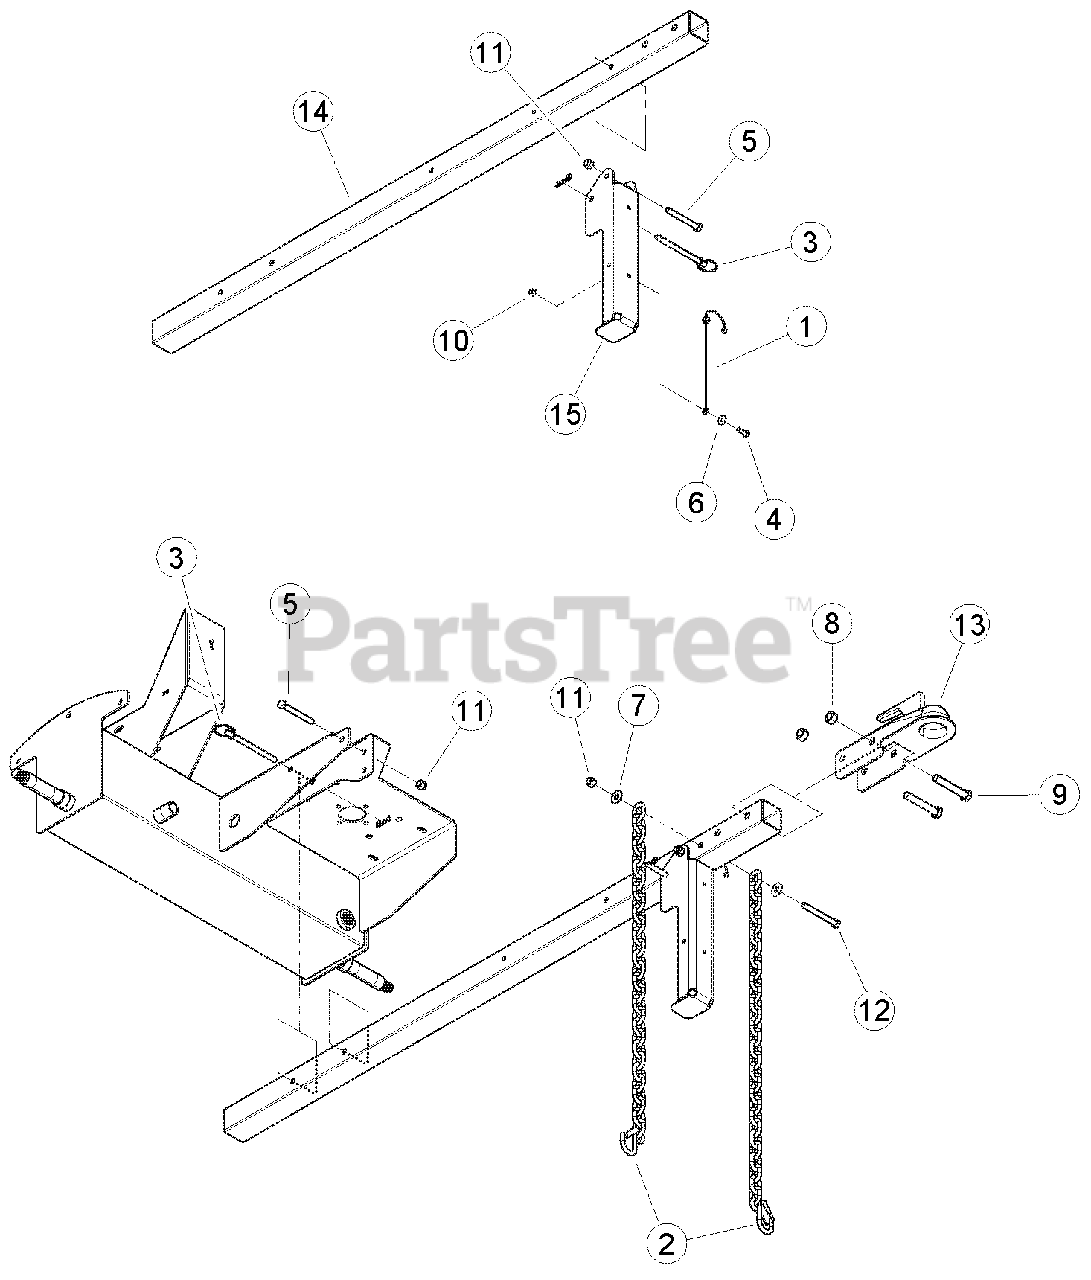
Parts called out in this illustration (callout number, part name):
1	LANYARD, NYLON
2	CHAIN, SAFETY 5000 LB W/LATCH
3	PIN, 3/8 HITCH
4	BOLT, 1/4 X 3/4 HEX HD GR5 ZP
5	BOLT, 3/8 X 3 HEX HD GR5 ZP
6	WASHER, 1/4 FLAT ZP
7	WASHER, 3/8 FLAT ZP
8	NUT, 1/2 CENTERLOCK GRB ZP
9	BOLT, 1/2 X 3 HEX HD GR5 ZP
10	NUT, 1/4 NE NYLOCK ZP
11	NUT, 3/8 NE NYLOCK ZP
12	BOLT, 3/8 X 3-1/4 HEX HD GR5 ZP
13	TRAILER HITCH COUPLER
14	TUBING, HITCH POLE
15	STAND, JACK
